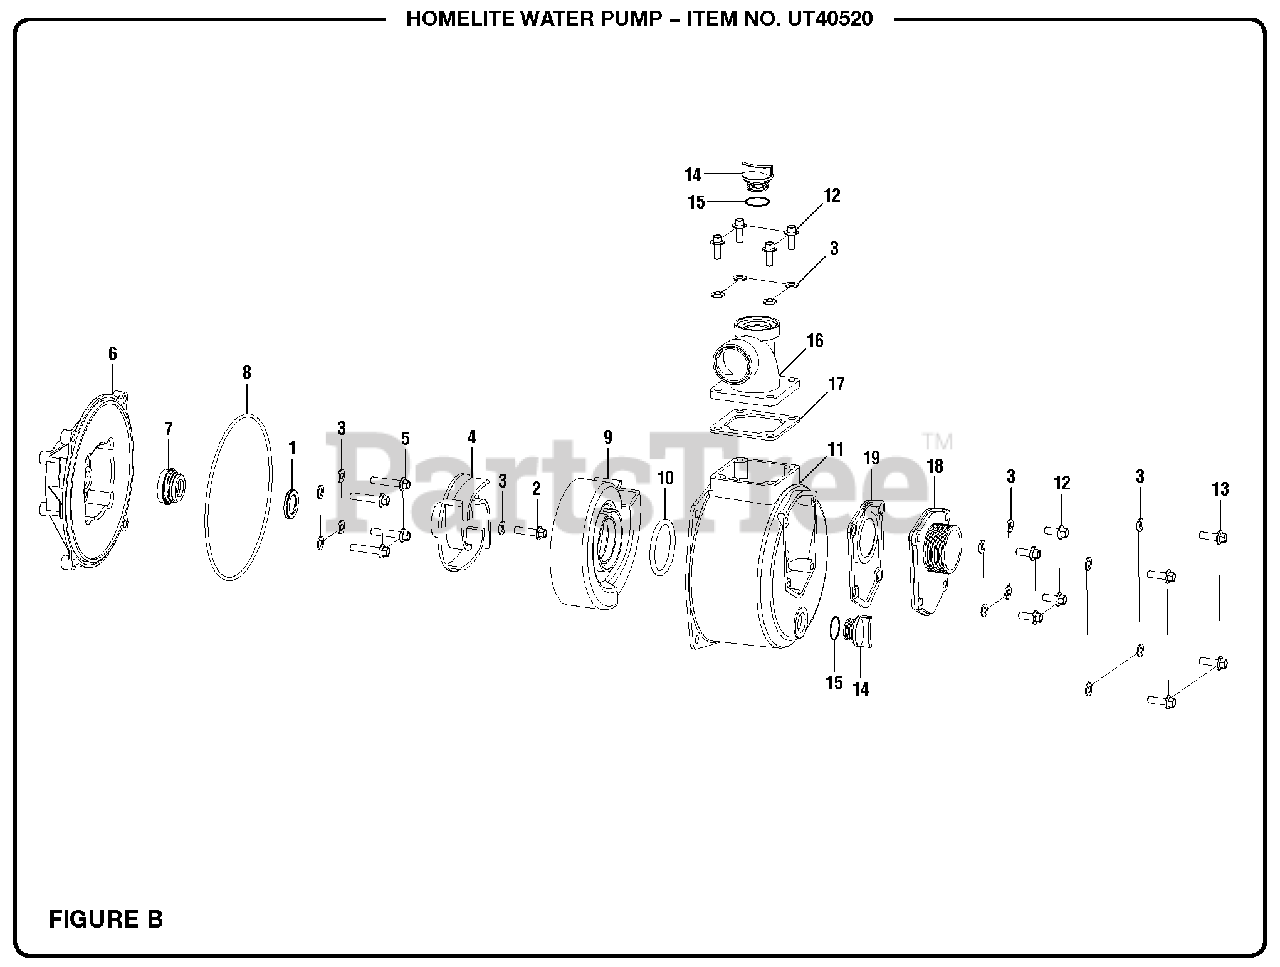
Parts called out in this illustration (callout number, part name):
1	Ceramic Seal Assembly
2	Bolt (5/16-24 x 30 mm)
3	Seal Washer
5	Bolt (5/16-24 x 40 mm, Flange Hd)
6	Housing Cover
7	Mechanical Seal Assembly
8	O-Ring (Housing Cover)
9	Pump Volute
10	O-Ring (Volute)
11	Pump Housing
12	Bolt (M8 x 20 mm, Flange Hd.)
13	Bolt (M8 x 25 mm, Flange Hd.)
14	Pump Plug
15	O-Ring (Plug)
16	Pump Outlet
17	Gasket (Outlet)
18	Pump Inlet
19	Check Valve
